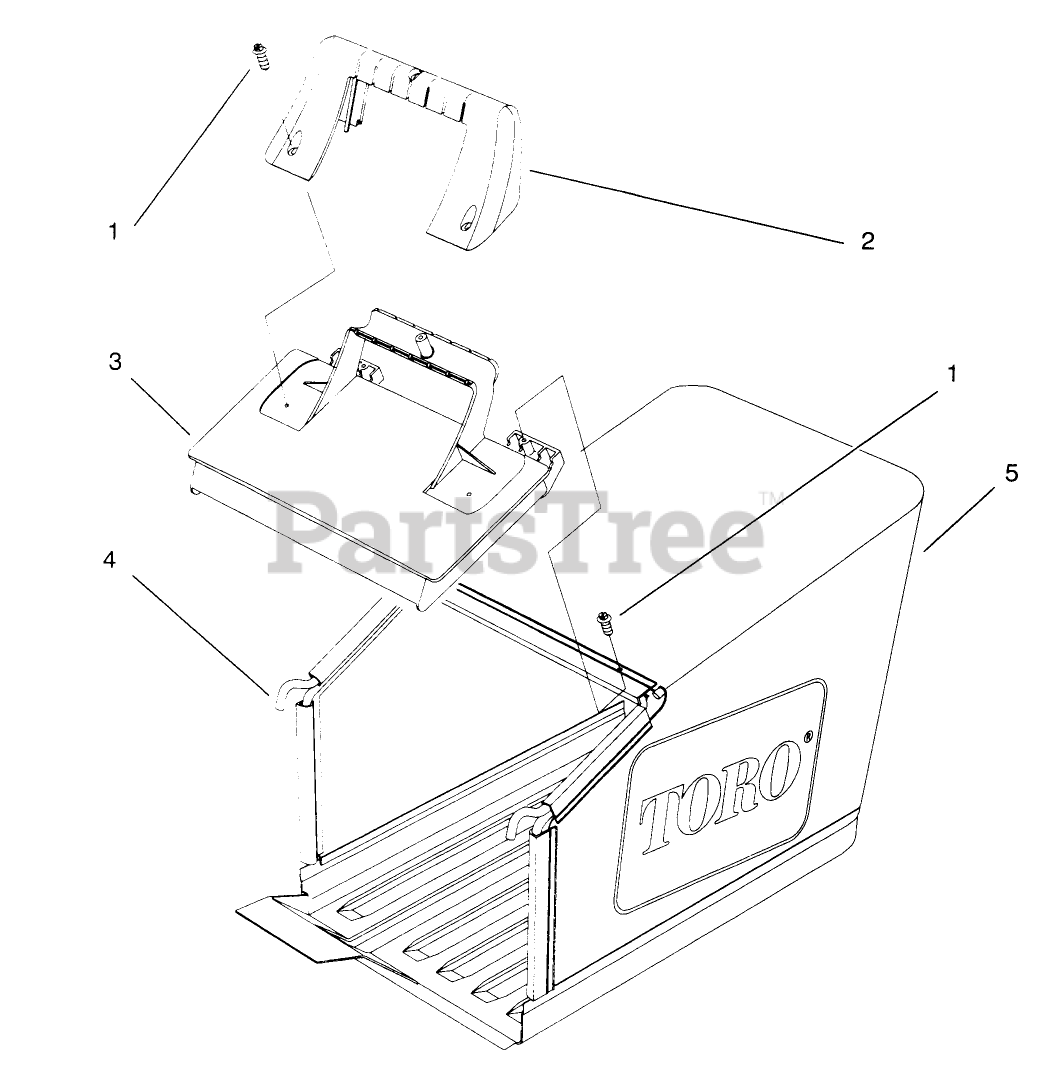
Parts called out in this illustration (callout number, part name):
1	SCREW-PPH
2	HANDLE-DOOR
3	DOOR-BAG
5	GRASS BAG 48CM W/PAN
